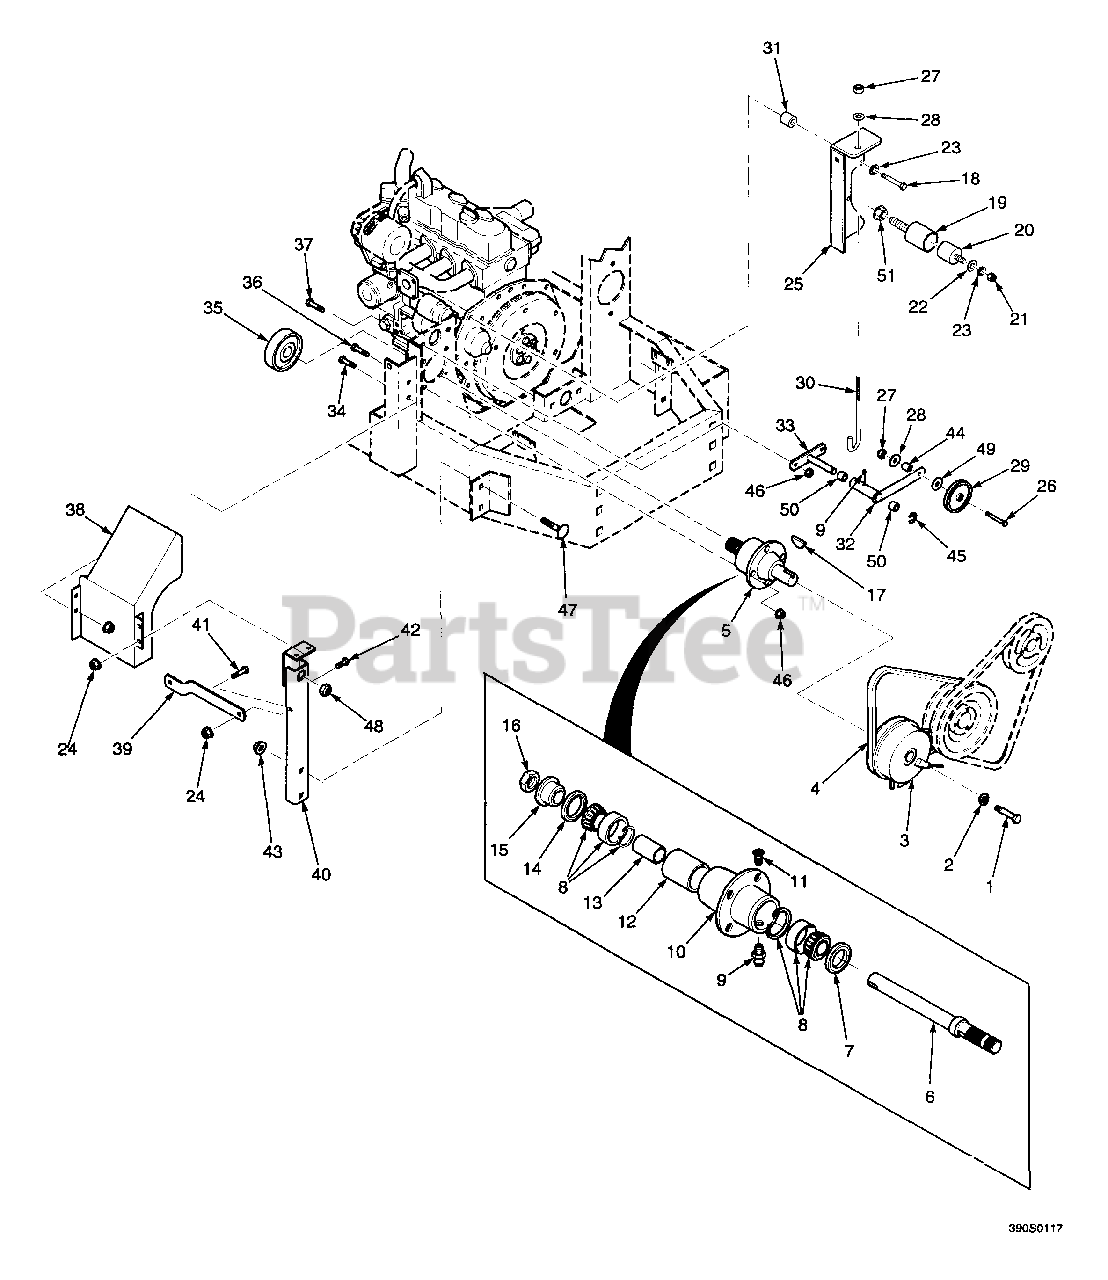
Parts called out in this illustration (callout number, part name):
1	Bolt, Hex Head, 7/16-20 x 2-1/2
2	Lockwasher, 7/16
3	Clutch, Electric
4	Belt, Deck Drive
5	Spindle, Deck Drive
6	Shaft, Deck Drive
7	Seal, 2.00 O.D. 1-1/2 Bore
8	Roller Bearing
9	Grease Fitting
10	Housing, Spindle
11	Relief Fitting
12	Spacer, Outside
13	Spacer, Inside
14	Seal, 2.00 O.D. x 1-5/8 Bore
15	Spindle Bushing, Bottom
16	Nut, 1-1/16-18
17	Key, #807 Woodruff, 1/4 x 7/8
18	Bolt, Hex Head, M8-1.25 x 40
19	Base, Anti-Rotation-Clutch
20	Isolator, Rubber
21	Nut, Hex,5/16-18
22	Flatwasher, 5/16 (.375 x .875 x .083)
23	Lockwasher, 5/16
24	Serr. Fl. Hex Nut, 5/16-18
25	Anchor Bracket, J-Bolt
26	Bolt, Hex Head, 3/8-16 x 2-1/4
27	Hex Locknut, Elastic Stop, 3/8-16
28	Flatwasher, 3/8 (.391 x .938 x .105)
29	Pulley, Idler
30	Rod, J-Hook
31	Spacer
32	Idler Arm, Clutch
33	Bracket, Idler Pivot
34	Serr. Fl. Hex Head Capscrew, 5/16-18 x 3/4
35	Hub, Brake
36	Bolt, Hex Head, 5/16-18 x 1-1/4
37	Serr. Fl. Hex Head Capscrew, 5/16-18 x 1-1/2
38	Belt Guard, Electric Clutch
39	Brace, Fan Support - LH
40	Upright, Fan Support - LH
41	Serr. Fl. Hex Head Capscrew, 3/8-16 x 1
42	Carriage Bolt, 5/16-18 x 3/4
43	Serr. Fl. Hex Nut, 1/2-13
44	Spacer, J Pull Rod
45	Retaining Ring, 75 Ext
46	Serr. Fl. Hex Nut, 5/16-18
47	Carriage Bolt, 1/2-13 x 1-1/4
48	Lock Nut, Elastic Stop, 1/2-13
49	Flat Washer, 3/8 (.406 x 1.50 x .179)
50	Bushing, Oilite - .753 I.D.
51	Nut, 7/16-14 Serr Flg
